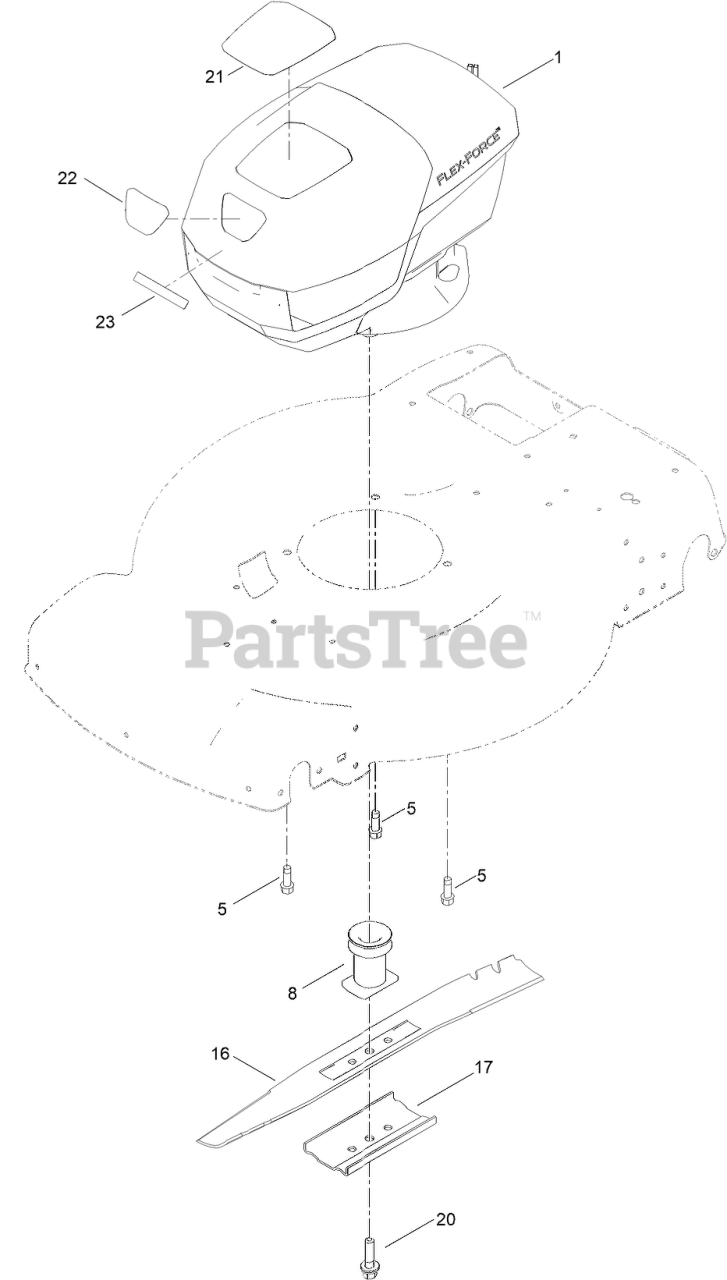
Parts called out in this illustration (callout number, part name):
1	MOTOR MODULE (60V)
5	SCREW-THD FORM, HWH
8	RETAINER-BLADE
16	BLADE [BLACK]
17	SUPPORT-BLADE
20	BOLT-BLADE
